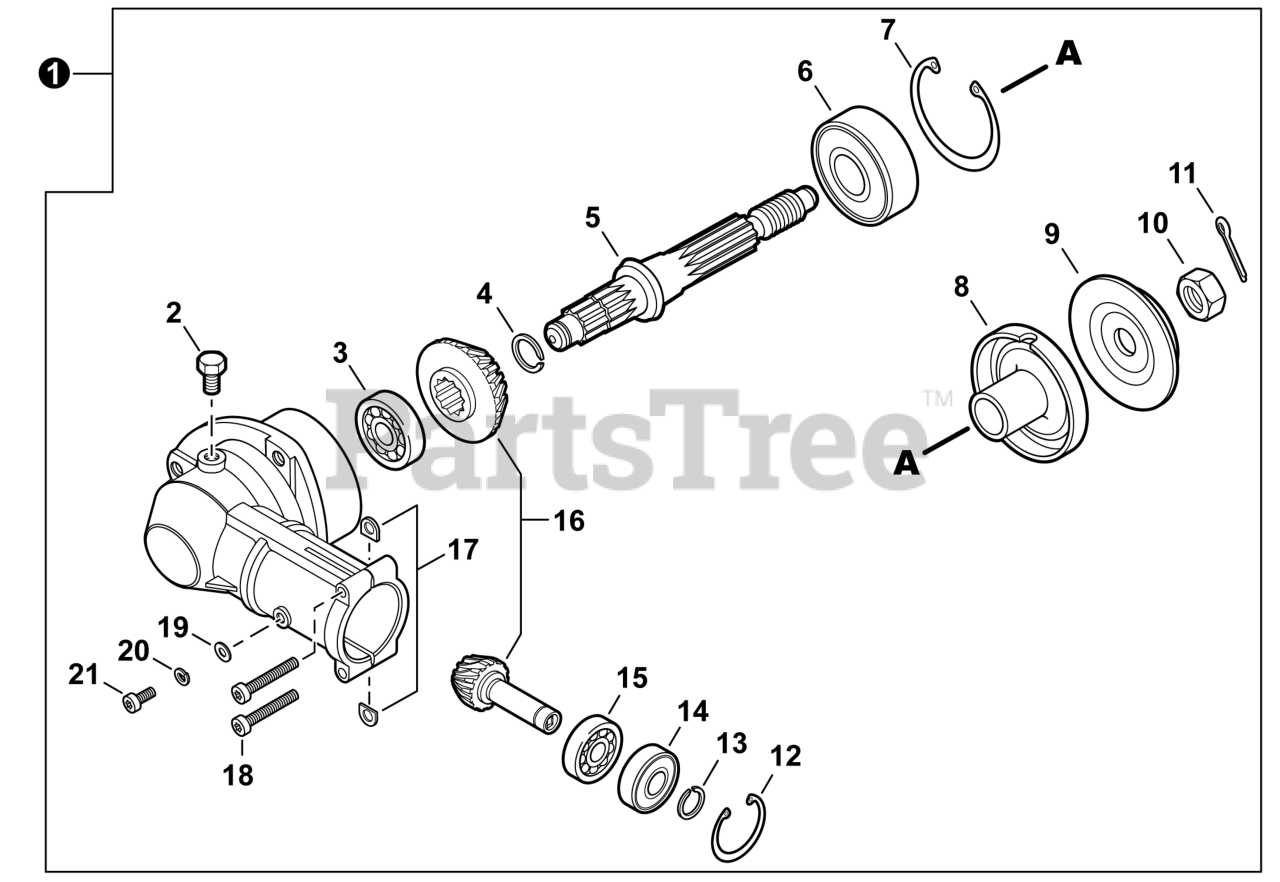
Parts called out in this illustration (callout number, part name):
1	GEAR CASE ASSY
2	BOLT M8x8
3	BEARING, BALL 629
4	RING, SNAP 12
5	SHAFT, GEAR
6	BEARING, BALL 6302
7	RING, SNAP 42
8	PLATE, ADAPTOR - UPPER
9	PLATE, ADAPTOR - LOWER
10	NUT 10x1.25 LH
11	PIN, COTTER 2x22
12	RING, SNAP 22
13	RING, SNAP 10
14	BEARING, BALL 6900Z
15	BEARING, BALL 6900
16	GEAR SET
17	D-WASHER
18	BOLT, TORX 5x25
19	WASHER, FLAT 5.5x10x0.8
20	WASHER, SPRING 5
21	BOLT, TORX 5x10
